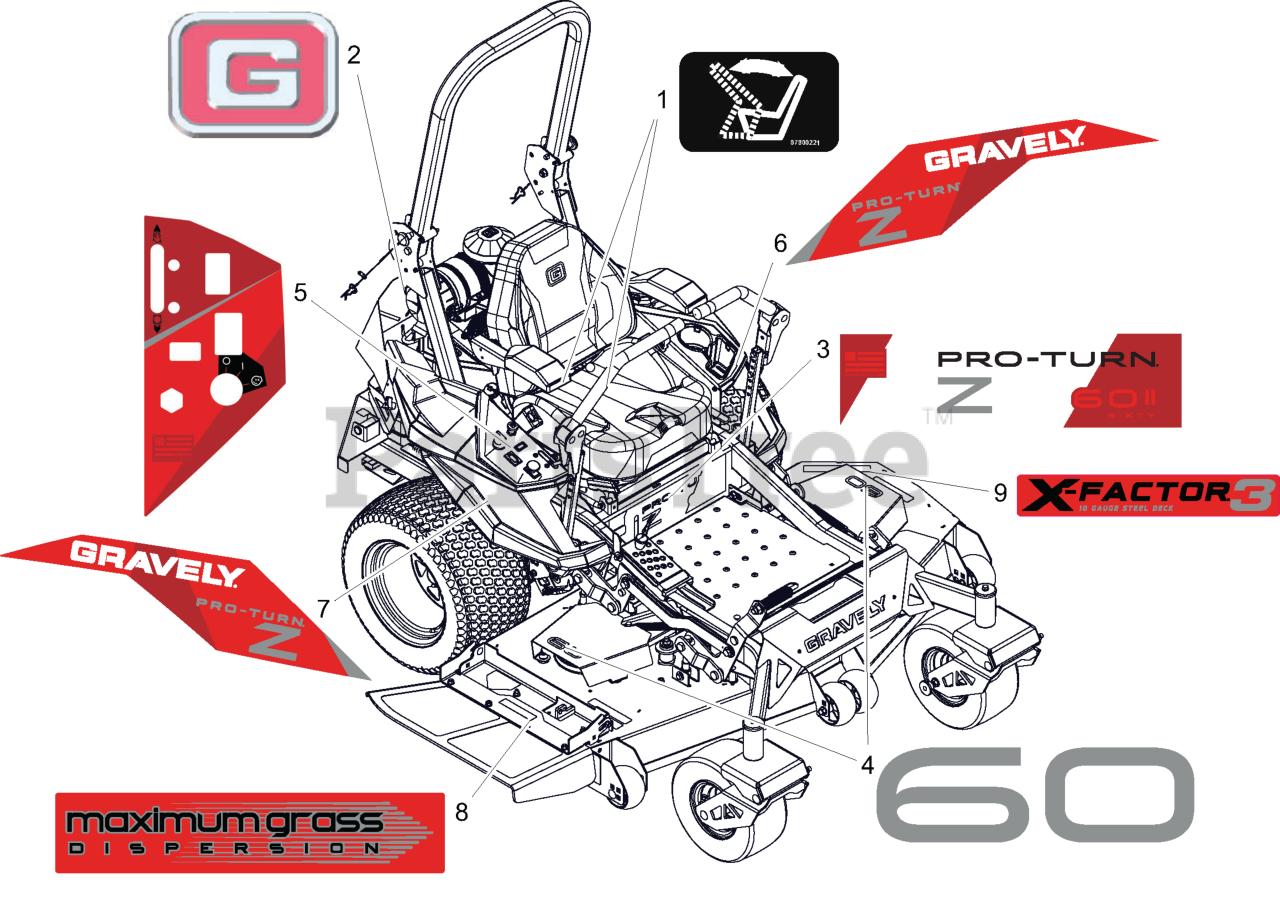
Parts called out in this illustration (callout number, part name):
1	DECAL - SEAT RELEASE
2	DECAL, GRAVELY BRAND
3	DECAL, PTZ - 60
4	DECAL, DECK - 60
5	DECAL, CONTROL PANEL
6	DECAL, FENDER LH - PTZ
7	DECAL, FENDER RH - PTZ
8	DECAL, DECK - MAX GRASS
9	DECAL, X-FACTOR 3
